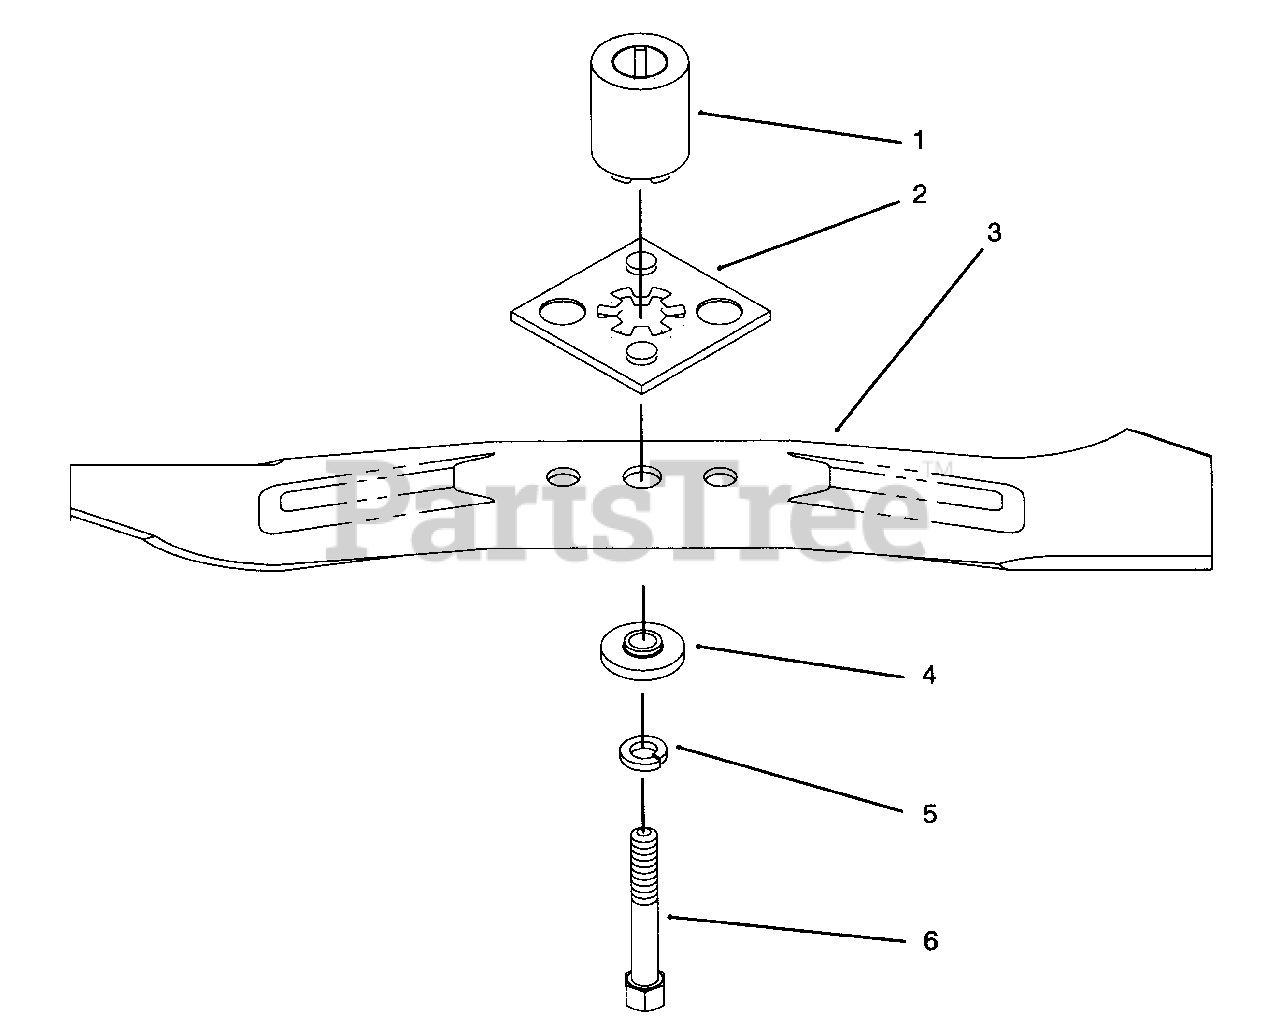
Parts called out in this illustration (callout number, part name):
1	Hub-Blade Driver
2	Plate-Blade Driver
3	Blade-48cm
4	Spacer-Blade
5	Washer-Lock
6	Bolt-Blade
